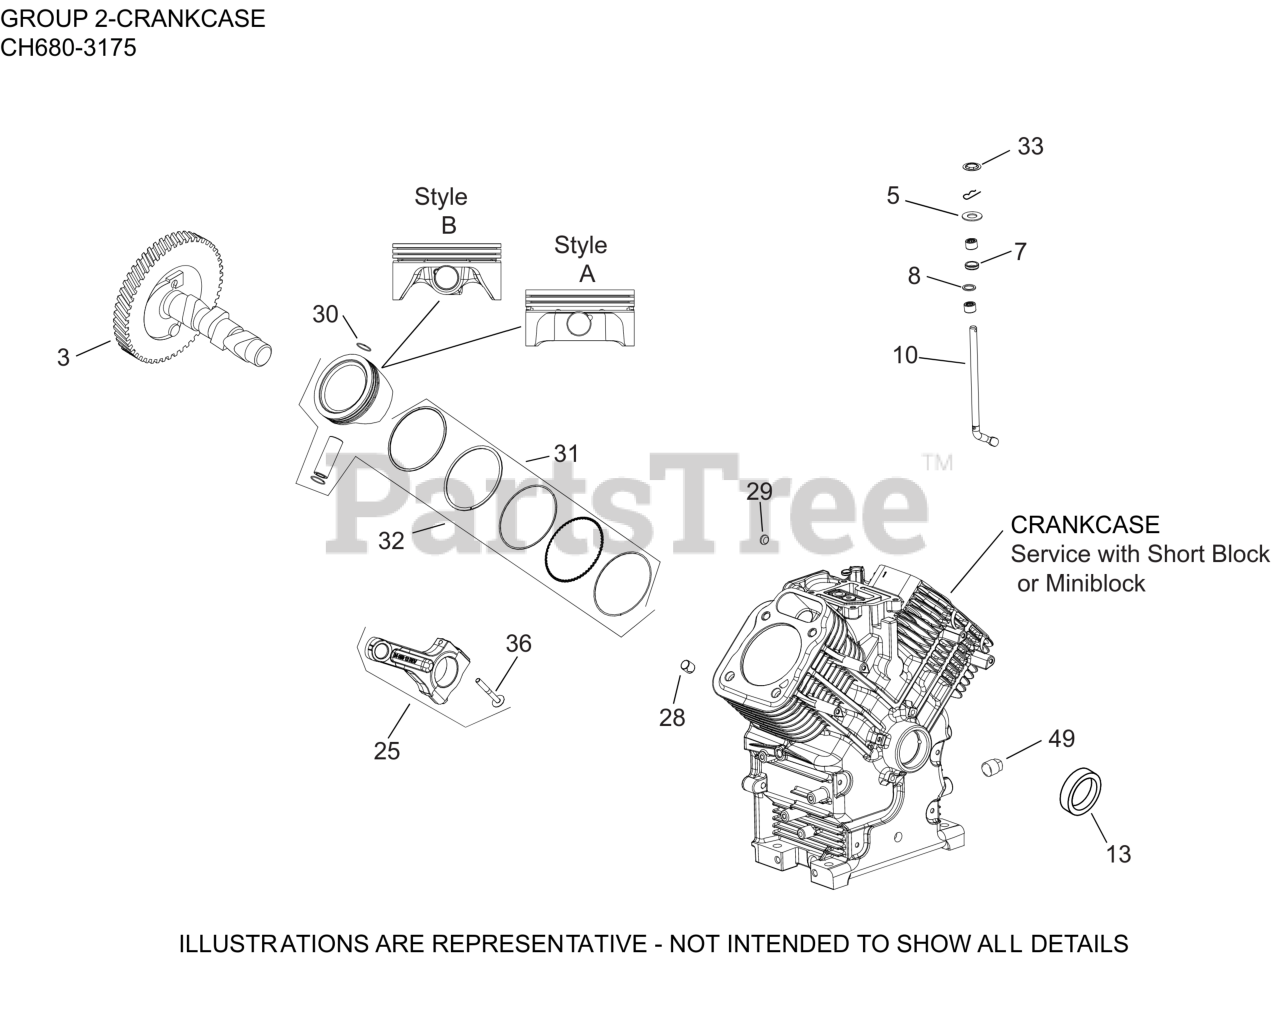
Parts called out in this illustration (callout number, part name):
3	KIT, CAMSHAFT
5	WASHER, FLAT 9 MM
7	SEAL, GOVERNOR CROSS SHAFT
8	WASHER, FLAT 11/32"
10	SHAFT, GOVERNOR CROSS
13	SEAL, OIL (HELIX LIP)
25	ROD, ASSEMBLY CONNECTING
28	PIN, LOCATING
29	PLUG, CUP
30	RETAINER, PISTON PIN
31	RING SET (STD) STYLE B
31	RING SET (.08) STYLE B
31	RING SET (.25) STYLE B
31	RING SET (.50) STYLE B
32	KIT, PISTON (STD) STYLE B
32	KIT, PISTON (.08) STYLE B-(#DSC)
32	KIT, PISTON (.25) STYLE B
32	KIT, PISTON (.50) STYLE B
33	RETAINER, RING
36	KIT, ROD BOLTS-(#25086677S)
49	PLUG, SQ HD PIPE 3/8"
